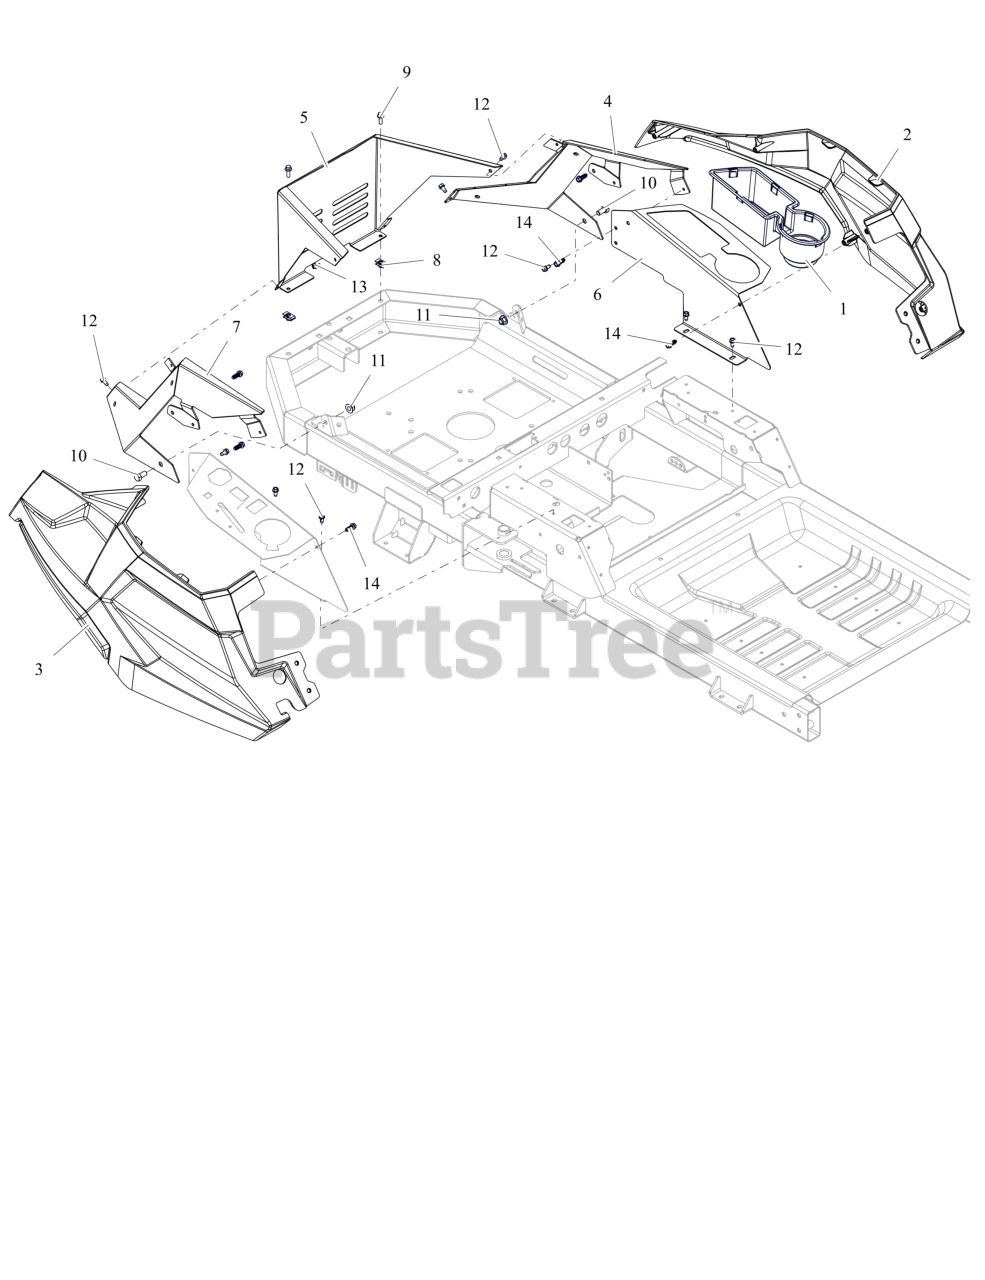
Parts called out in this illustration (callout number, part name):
1	INSERT, CUP/STORAGE HOLDER
2	FENDER, LH
3	FENDER, RH
4	WRAP, REAR - LH (RED)
5	WRAP, REAR (BLACK)
6	PANEL, CUP HOLDER (RED)
7	WRAP, REAR - RH (RED)
8	NUT-RTNR .25-20X.56
9	BLT,HEX-FLG .25-20X.75 G5 BFP
10	BLT,HEX .38-16X.75 G5 ZCC
11	NUT,NYL-FLG .38-16 GF ZCC
12	SCR-TAP .25-20X.50 HWH ZCC
13	SCR,TAP .25-20X.375 HWH TR ZCC
14	SCR-.312X.75 #14H H/W/H H/L CZ
